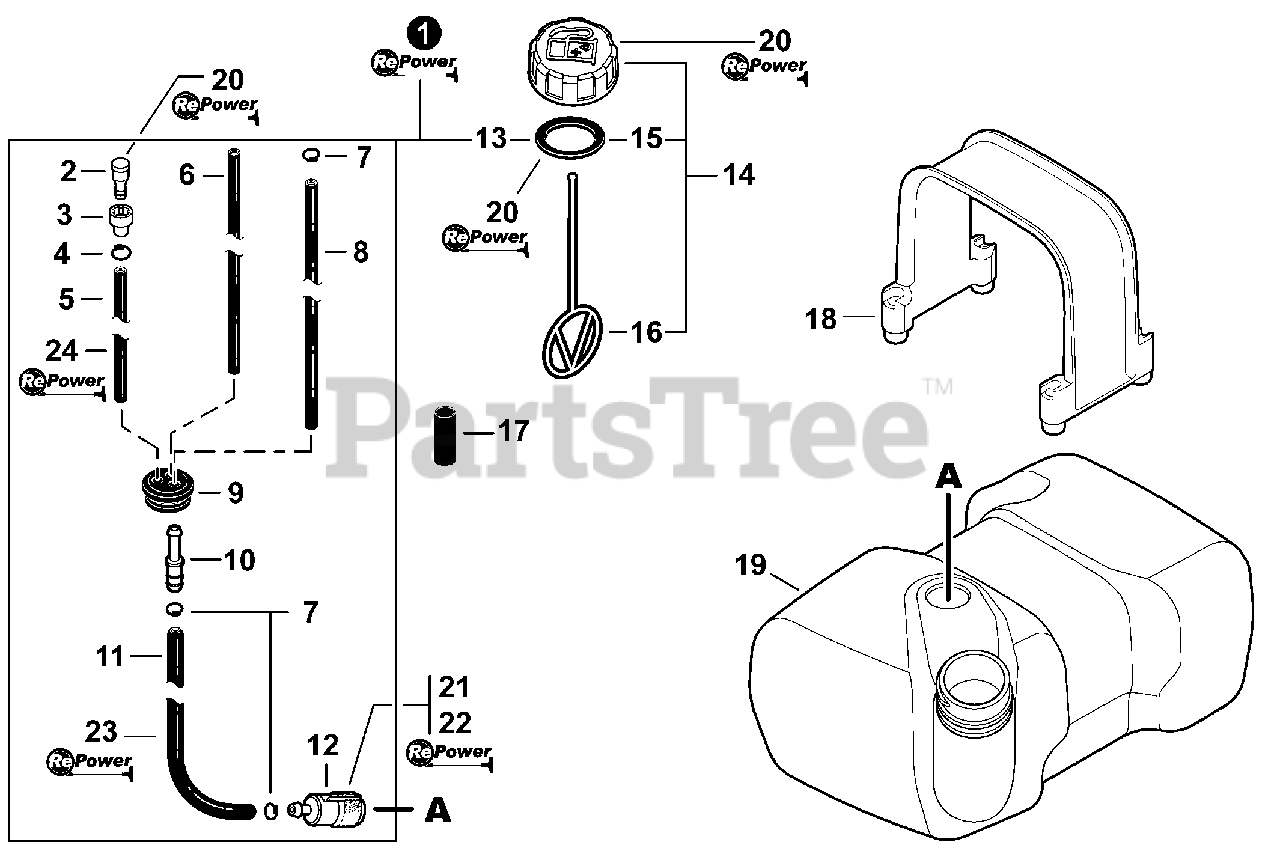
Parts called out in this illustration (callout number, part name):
1	FUEL SYSTEM KIT
2	VENT ASSY
3	HOLDER, VENT
4	CLIP Ø6.5 MM
5	PIPE, FUEL 3×6×130 BLACK
6	PIPE, FUEL 2.4×5×200 BLACK
7	CLIP Ø6
8	PIPE, FUEL 3×5×135L BLACK
9	GROMMET, FUEL
10	CONNECTOR, PIPE Ø5ר3.5
11	PIPE, FUEL 3×5×105L BLACK
12	FILTER, FUEL
13	GASKET, FUEL CAP
14	CAP ASSY, FUEL
15	GASKET, FUEL CAP
16	CONNECTOR, CAP L= 100 MM
17	TUBE, FUEL LINE 16×18×L40
18	RETAINER, FUEL TANK
19	TANK, FUEL
20	CAP/VENT KIT - REPOWER
21	TUNE-UP KIT - REPOWER
22	FILTER KIT - REPOWER
23	BULK PIPE - 3×5 MM BLACK (4 PIECES×2 M)
24	BULK PIPE - 3×6 MM BLACK (4 PIECES×2 M)
